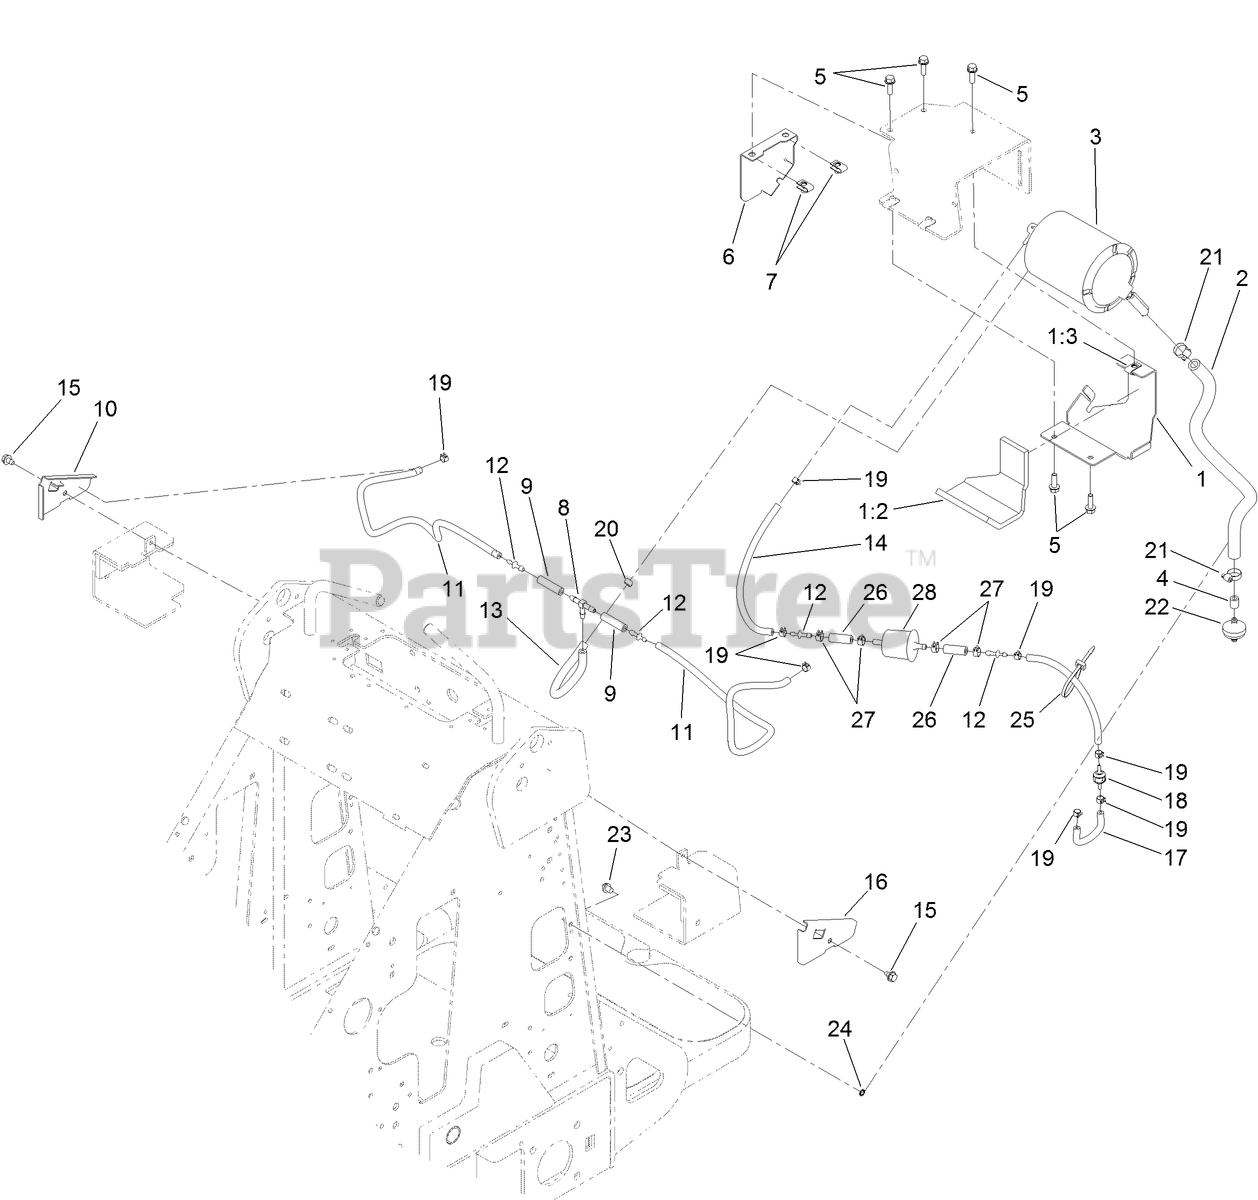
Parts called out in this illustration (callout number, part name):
1	CANISTER MOUNT ASM
1:2	PAD-FOAM
1:3	NUT-CLIP, U
2	HOSE-VENT
3	CANISTER-CARBON, 1200CC
4	HOSE-FUEL
5	SCREW-HHF
6	COVER-CANISTER
7	NUT-CLIP, U
8	FITTING-TEE, BARBED
9	HOSE-FUEL
10	PLATE-HOSE RETAINER, RH
11	HOSE-FUEL
12	FITTING-STRAIGHT
13	HOSE-FUEL
14	HOSE-FUEL
15	SCREW
16	PLATE-HOSE RETAINER, LH
17	HOSE-FUEL
18	VALVE-CHECK, VACUUM
19	CLAMP-HOSE
20	CLAMP-HOSE
21	CLAMP-HOSE
22	FILTER-FUEL, INLINE
23	CLIP-TIE
24	WASHER-LOCK
25	TIE-CABLE
26	HOSE-FUEL
27	CLAMP-HOSE
28	FILTER-FUEL
